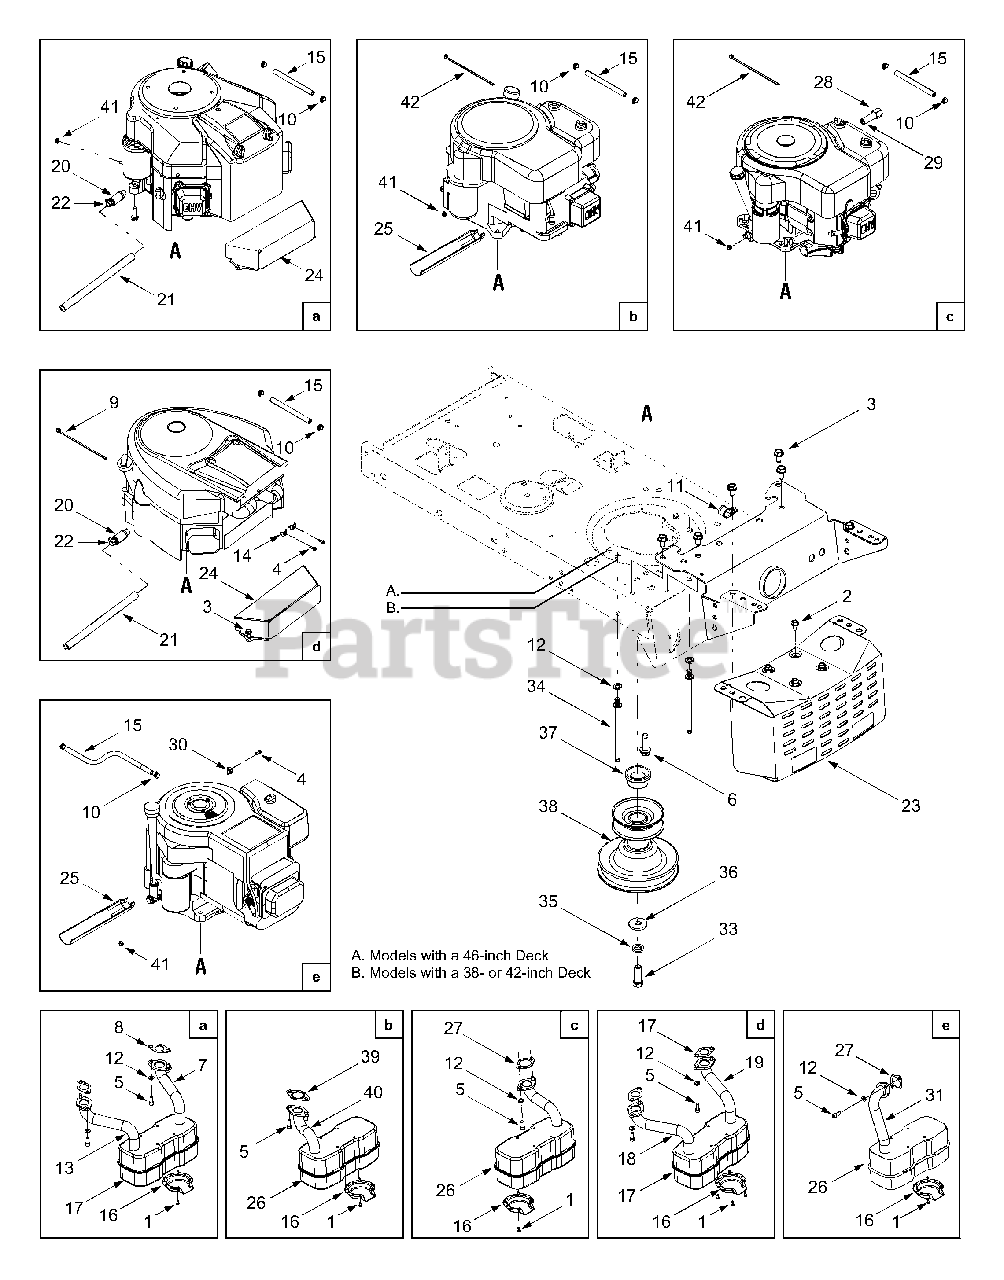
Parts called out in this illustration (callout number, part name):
1	Screw, #8-32 x .375
2	Self-tapping Screw, 1/4-20 x .5
3	Self-tapping Screw, 5/16-12 x .75
4	Screw, #10-32 x .625
5	Socket Cap Screw, 5/16-18 x .625
6	Self-tapping Screw, 3/8-16 x 1.25
7	LH Exhaust Pipe
8	Exhaust Gasket
9	Push-mount Cable Tie, 7.5
10	Hose Clamp, .490
11	Clamp, 9/16
12	Lock Washer, 5/16
13	RH Exhaust Pipe
14	Casing Clamp
15	Fuel Line Hose
16	Muffler Deflector
17	Muffler, Twin Inlet
18	RH Exhaust Pipe
19	LH Exhaust Pipe
20	Oil Drain Valve
21	Oil Drain Hose
22	Oil Drain Cap
24	Engine Heat Shield
25	Oil Drain Sleeve
26	Muffer, Single Inlet
27	Exhaust Gasket
28	Oil Drain Cap, 3/8-18
29	Oil Drain Pipe, 3/8-16 x 2.0
30	Casing Clamp
31	Exhaust Pipe
33	Hex Screw, 7/16-20 x 1.25
34	Belt Keeper Pin, 5/16 x 4.75
35	Lock Washer, 7/16
36	Flat Washer, .450 x 1.25 x .164
37	Spacer, 1.0 x 1.4 x .825
38	Engine Pulley, 3.56 x 5.56
39	Exhaust Gasket
40	Exhaust Pipe
41	Hex Sems Nut, 1/4-20
42	Cable Tie, 7.4"
